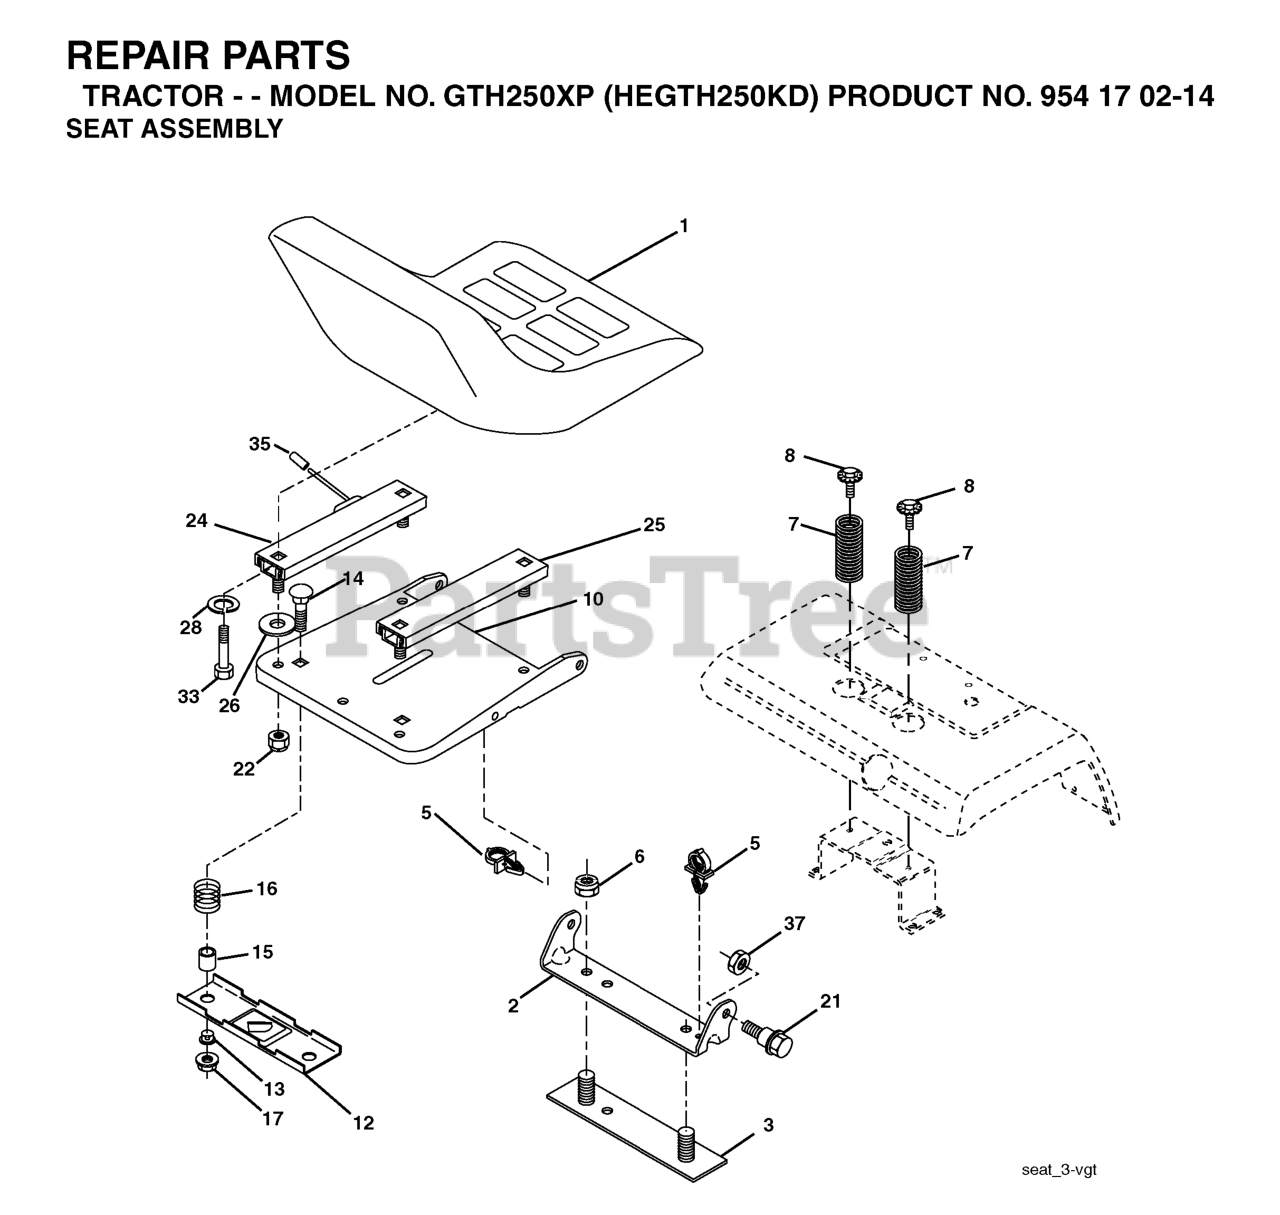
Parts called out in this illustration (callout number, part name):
1	SEAT
2	SEAT PIVOT BRKT
3	STRAP
6	NUT
7	SPRING COMPRESSION
8	BOLT.5/16-18UNCX3/4 W/SEMS.BLK
10	PAN SEAT
12	BRKT SWITCH
14	BOLT.ROUND.HEAD.SQUARE.NECK
15	SPACER SPLIT
16	SPRING COMPRESSED
17	NUT T
21	BOLT.SHOULDER.5/16-18
22	LOCKNUT
24	TRACK SLIDE, SEAT(L)
25	TRACK SLIDE, SEAT(R)
33	BOLT.FIN.HEX.5/16-18X3/4
35	CAP
37	NUT.71038.31-18.HEX.NYLOCK
